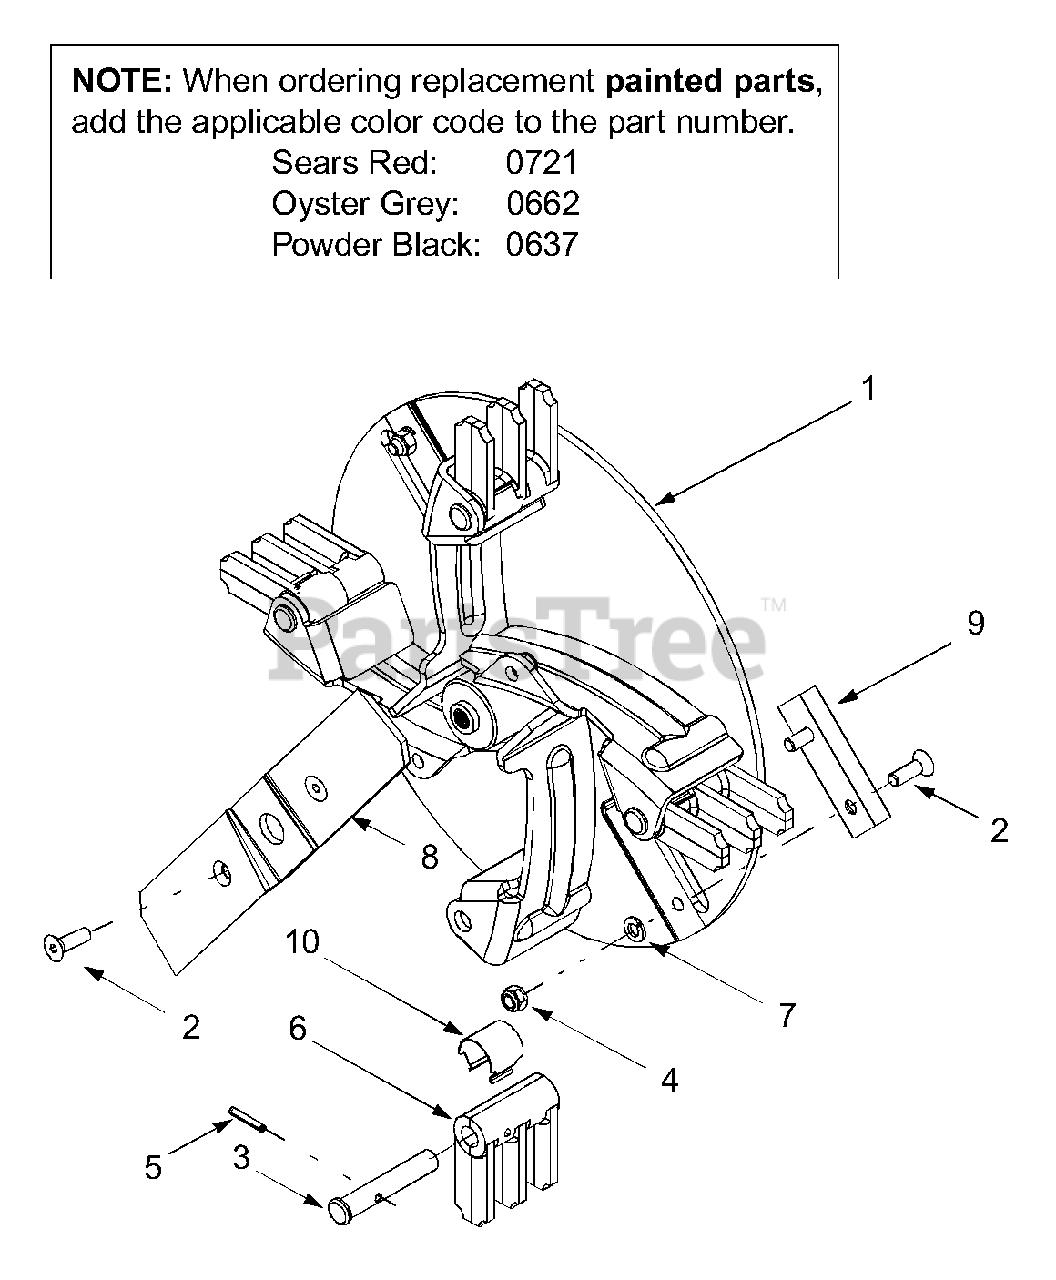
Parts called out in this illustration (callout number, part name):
1	Impeller Weldment
2	Machine Screw, 5/16-24 x 1.0
3	Clevis Pin, .496
4	Hex Lock Nut, 5/16-24
5	Spiral Pin, .156 x 1.0
6	Flail
7	Lock Washer, 5/16
8	Shredder Blade
9	Chipper Blade
10	Retainer Clip
